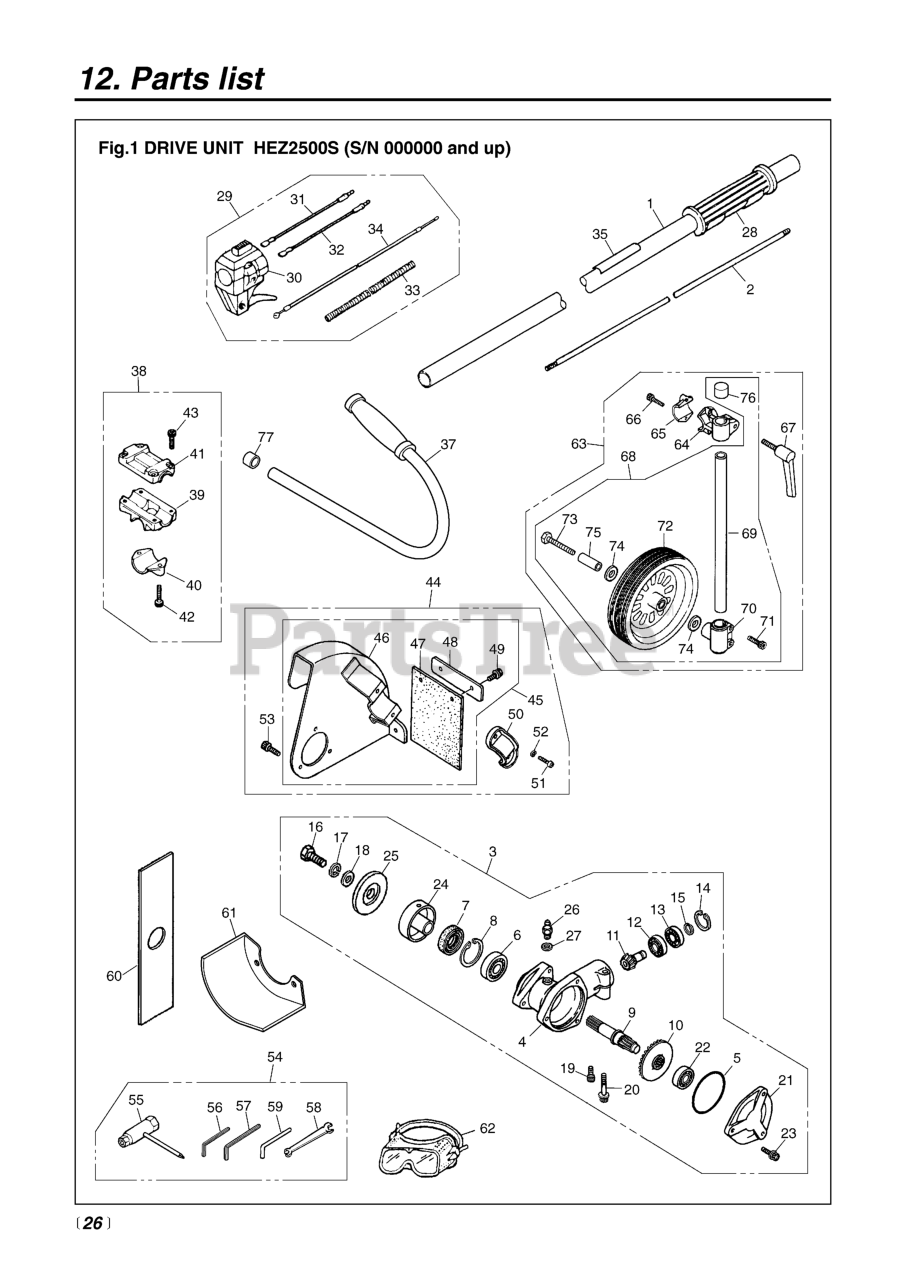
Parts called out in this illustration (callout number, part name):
1	PIPE COMP
2	SHAFT (RPLS -12212)
5	O-RING
7	SEAL, OIL
8	RING, SNAP, M32 x 1.2
9	SHAFT, GEAR
10	GEAR
11	PINION
12	BEARING (RPLS T3403-13530)
13	BEARING (RPLS T3300-13531)
14	RING, SNAP, M24 x 1.2
15	RING, SNAP (RPLS T3300-13330)
16	BOLT, LH
17	WASHER (RPLS 3180-13270)
18	WASHER, M8 x 2.3 (RPLS -20823)
19	BOLT, M5 x 12
20	BOLT, M6 x 1.35
21	COVER
22	BEARING (RPLS T3403-13510)
23	BOLT
24	HOLDER (A)
25	HOLDER (B)
26	FITTING, GREASE
27	WASHER, M6 X .8
28	GRIP (RPLS 3577-32140 & 3220-
30	LEVER (USE 848-8R2-0313)
31	CORD (A), BLACK
32	CORD (B), RED
33	TUBE (RPLS 4900-72141)
34	CABLE (RPLS 5580-83100)
35	NAME-PLATE
37	HANDLE, J
38	BRACKET ASSY (REPLACES -14100)
40	CAP, LOWER
41	CAP, UPPER (RPLS -14191)
42	BOLT, M5 X 22
43	BOLT, M5 X 25
45	COMP. GUARD
46	GUARD (RPLS 6367-24110)
47	PLATE (RUBBER)
48	PLATE (REPLACES -24130)
49	BOLT, M5 X 12
51	BOLT, M6 X 18
52	WASHER, M6 X 15
53	BOLT
55	SOCKET
56	WRENCH (TOOL)
57	WRENCH (TOOL)
58	SPANNER, 8 X 10 (RPLS 2540- )
59	BAR
60	BLADE, EDGER (RPLS 147315)
61	COVER (CAN USE 6367-96110)
62	GOGGLE
63	WHEEL ASSY COMP (RPLS -25000)
64	BRACKET
65	CAP, LOWER
66	BOLT, M5 X 22
67	LEVER
68	WHEEL ASSY (RPLS -25100)
69	PIPE
71	BOLT, M6 X 25
72	WHEEL
73	BOLT (REPLACES -81060)
74	WASHER, M10 x 1.6
75	SPACER, PIPE
76	CAP
77	CAP
